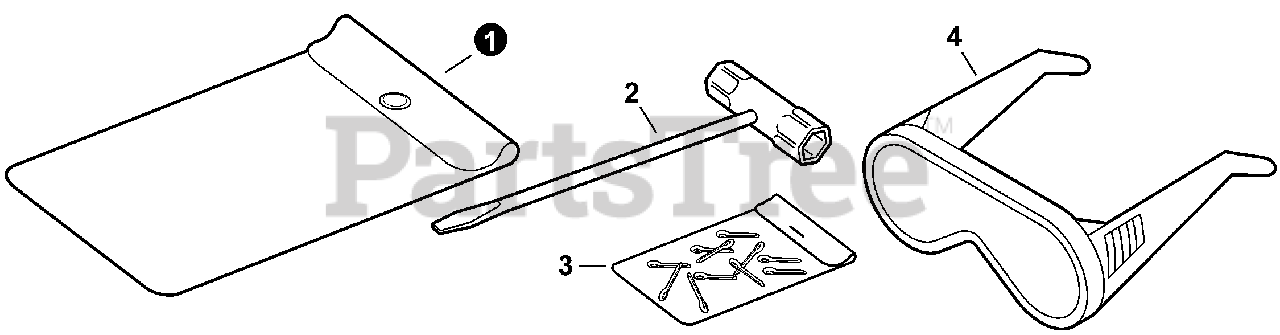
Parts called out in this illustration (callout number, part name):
1	BAG, TOOL
2	T-WRENCH
3	PIN, COTTER 2×22
4	GLASSES, SAFETY
